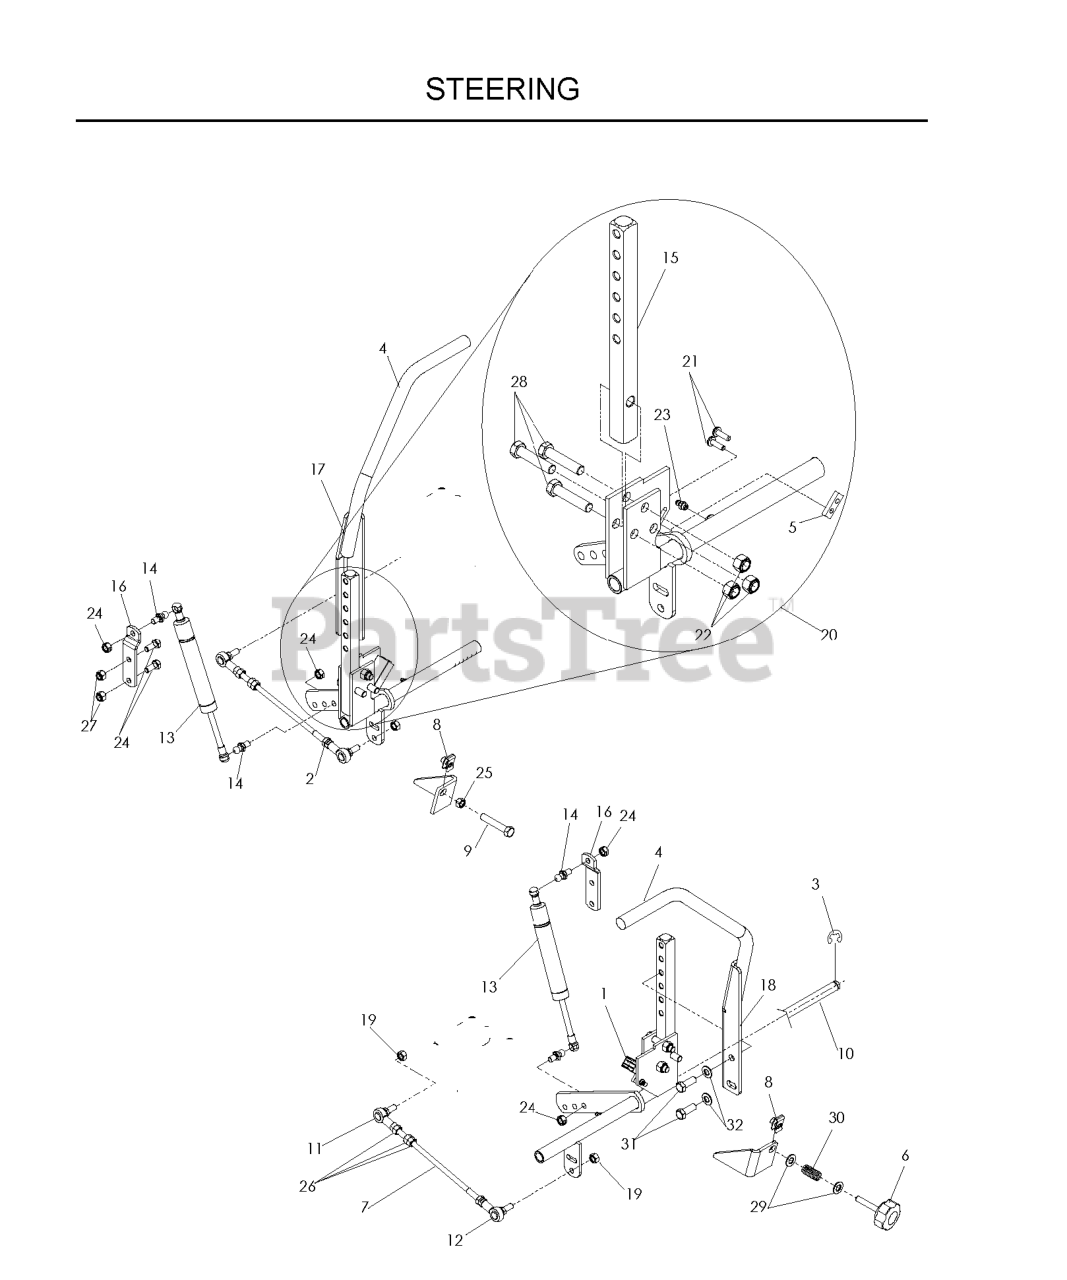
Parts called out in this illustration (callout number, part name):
1	SWITCH, INTERLOCK
2	NUT 5/16F LEFTHAND
3	E-RING 1/2 (2 2)
4	GRIP - DRIVE LEVER 12"
5	TAPPED PLATE
6	ADJUSTMENT KNOB
7	PUMP CONTROL LINK
8	U-CLIP 5/16-18 NUT RETAINER
9	HCS 5/16-18X1-3/4 TPBLT
10	CONTROL SHAFT
11	SPHERICAL ROD END, RH
12	SPHERICAL ROD END, LH
13	DAMPENER W/EXT SEAL
14	STUD.BALL.10MM
15	CONTROL ARM
16	DAMPENER ARM
17	RT DRIVE LEVER WLDMT
18	LT DRIVE LEVER WLDMT
19	NUT 5/16F NYLOC
20	CONTROL ASM - ADJ, LT
20	CONTROL ASM - ADJ, RT
21	SCREW #10-24 X 5/8
22	NUT 3/8-16 NYLOC
23	ZERK
24	NUT 5/16C CENTERLOCK
25	NUT 5/16C HEX
27	NUT 5/16 NYLOC
28	HCS 3/8-16 X 1 3/4 GR5
29	WASHER 5/16 FLAT
30	COMPRESSION SPRING
31	HCS 3/8-16X1.GRD.5.ZD
32	WASHER, 3/8 DISC SPRING SPEC
33	HCS 5/16C X 3/4
